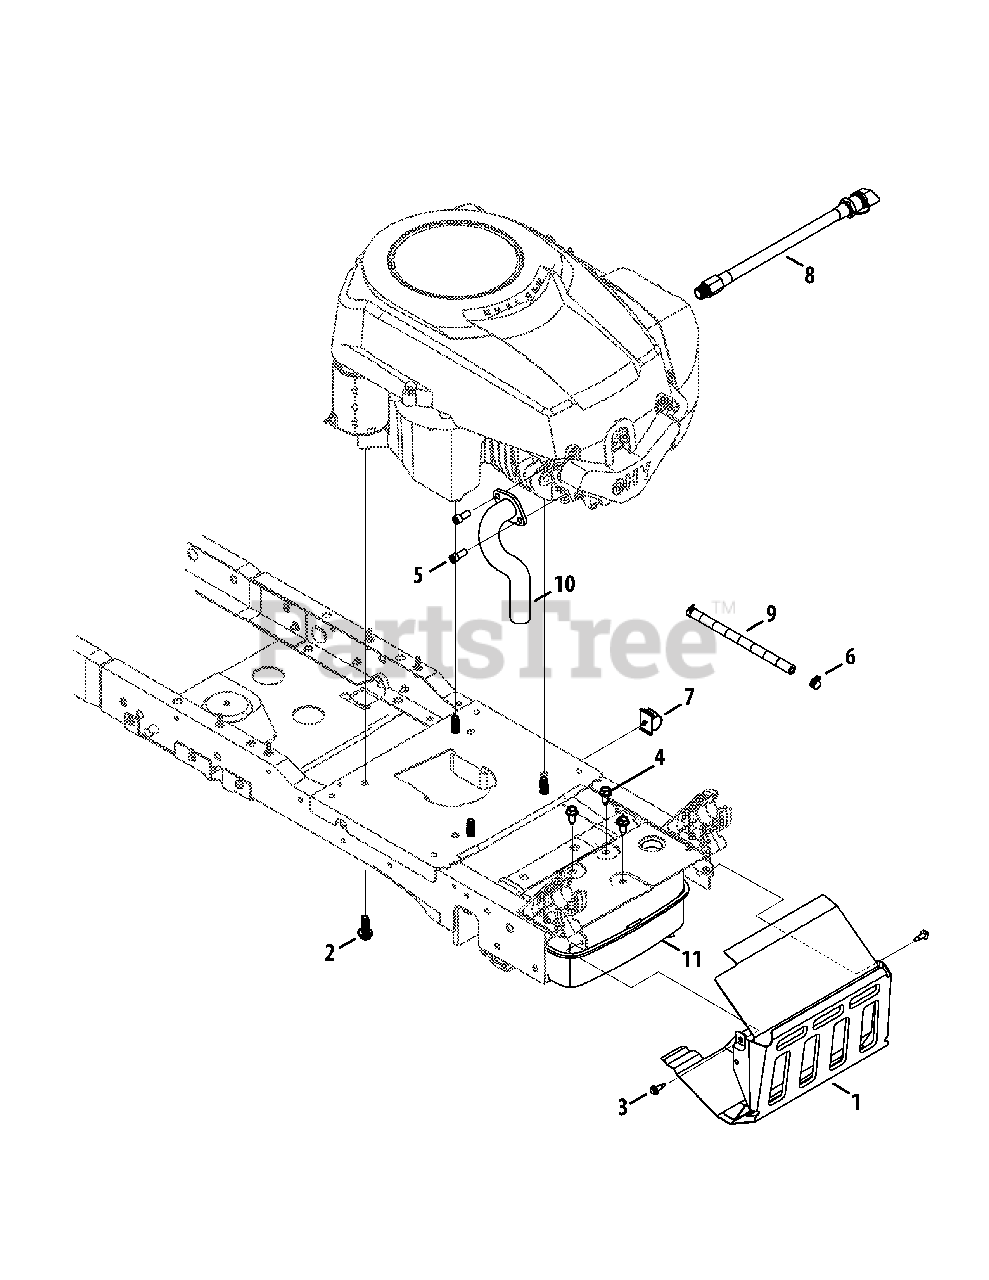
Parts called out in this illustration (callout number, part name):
1	Shield Ass’y, Muffler
2	Screw, Self-tapping, 3/8-16, 1.0
3	Screw, M6-1 x .625
4	Screw, Self-tapping, M8-1.25, .750
5	Screw, Sokt Head, 5/16-18, .750
6	Clamp, Hose, .490 Dia.
7	Push Mount Wire Clip, .750
8	Drain, Oil
9	Hose, Fuel, Low Permeation, 1/4
10	Exhaust Pipe
11	Muffler, Kohler
